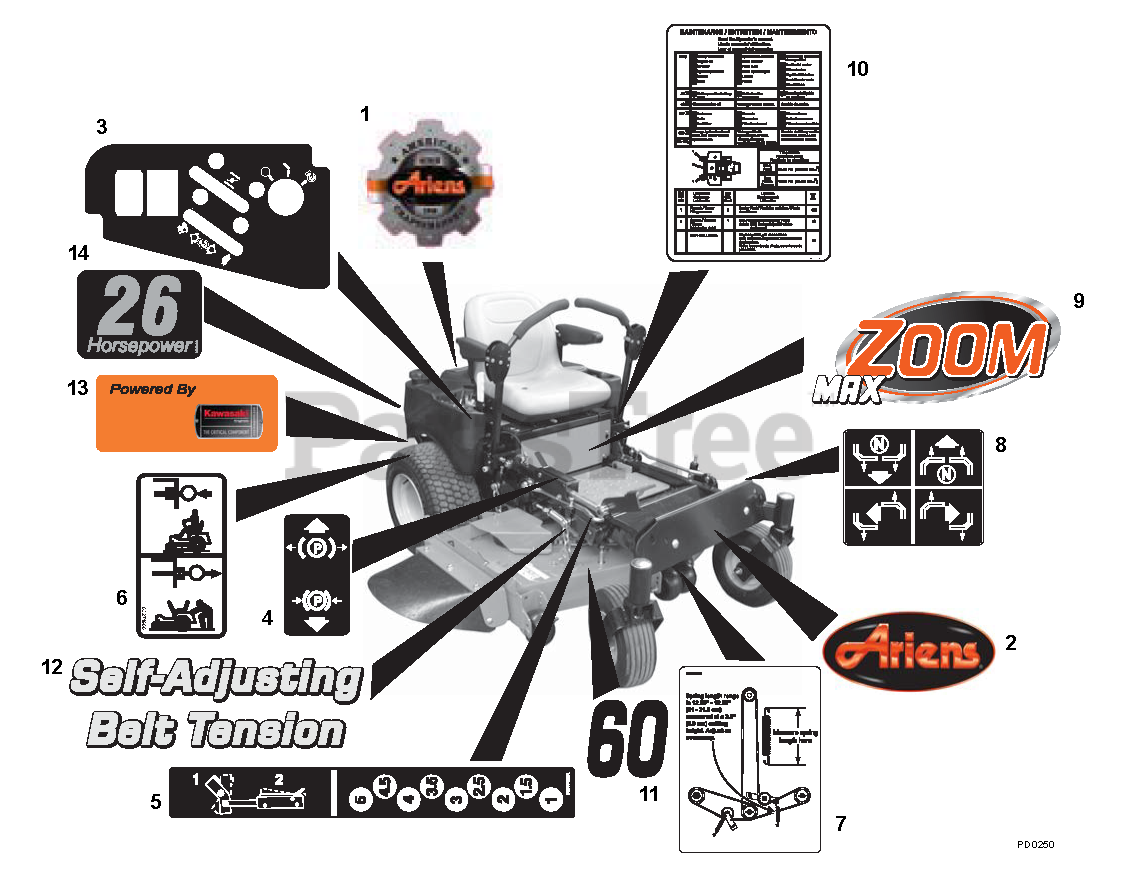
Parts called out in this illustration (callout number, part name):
1	Decal, Ariens Heritage Small
2	DECAL, ARIENS JEWEL
3	DECAL - CONTROL PANEL
4	DECAL, PARKING BRAKE LEVER
5	DECAL, HEIGHT OF CUT COMPACT-Z
6	DECAL, TRANSMISSION DISCONNECT
7	DECAL, BELT ROUTING
8	DECAL, INSTRUCTIONAL-STEERING
9	DECAL, MAX ZOOM
10	DECAL-MAINTENANCE INSTRUCTIONS
11	DECAL, 60"
12	DECAL, DECK FEATURE
13	DECAL, POWERED BY KAWASAKI
14	DECAL, 24HP
